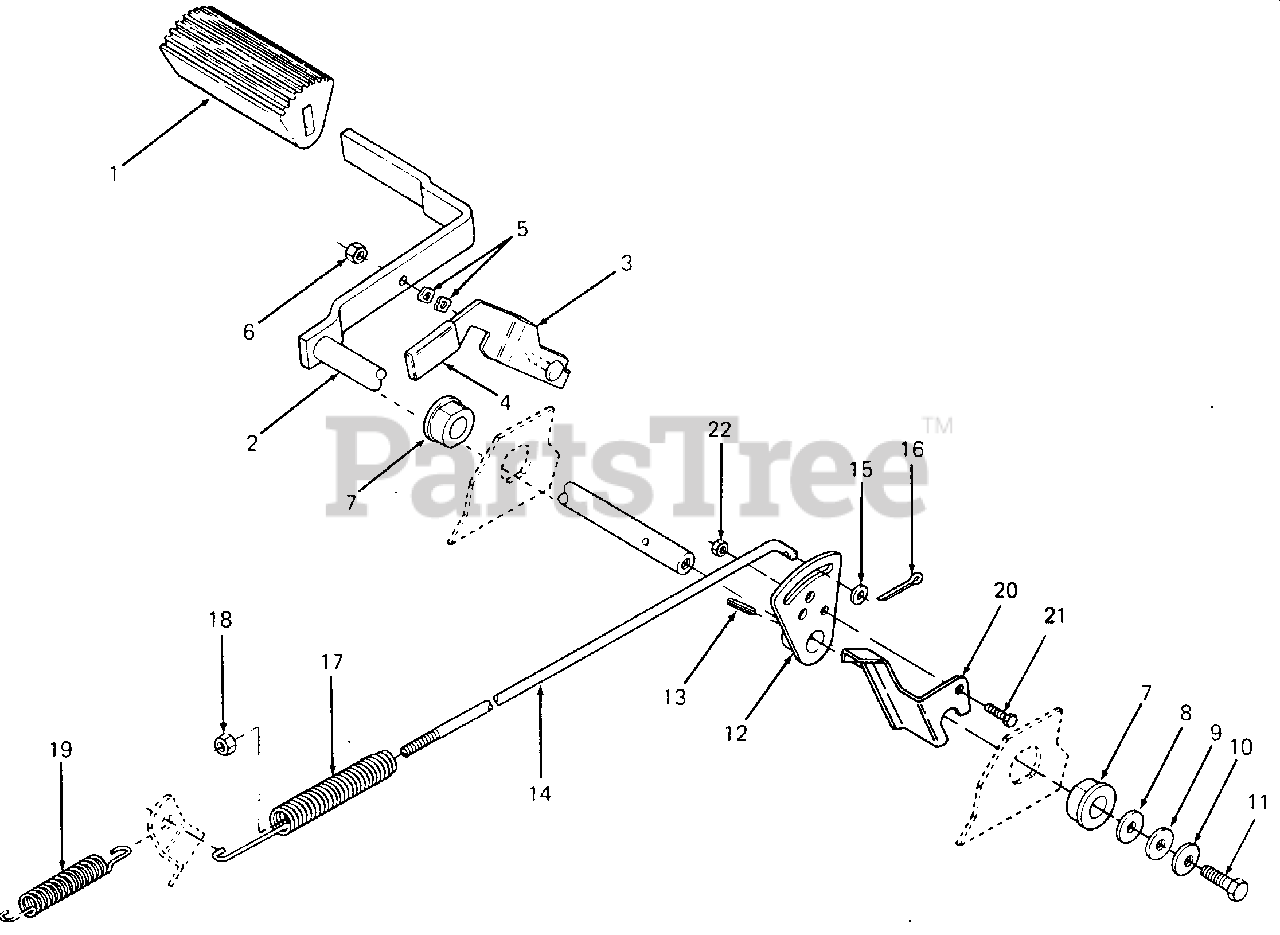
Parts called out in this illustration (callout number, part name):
1	Pad, Foot
5	Washer, Wave
6	Nut, Hex Insert Lock, 1/4-20
7	Bearing, Flange
8	Washer, Flat, .635 X 1.12 X .090 Thk
9	Washer, Flat, .26 X .93 X .120 Thk
10	Washer, Bell, .265 X .75 X .062 Thk
11	Screw, Hex Cap, 1/4-20 X .75 Lg GR5
12	Cam, Brake
13	Pin, Spiral Spring, 3/16 Dia X 1.5 Lg
14	Rod, Brake
15	Washer, Flat, .281 X .73 X .063 Thk
16	Pin, Cotter, 3/32 X .75 Lg
17	Spring, Ext
18	Nut, Hex Patch, 1/4-20
19	Spring, Brake Return
22	Nut, Hex Patch Lock, 1/4-20
